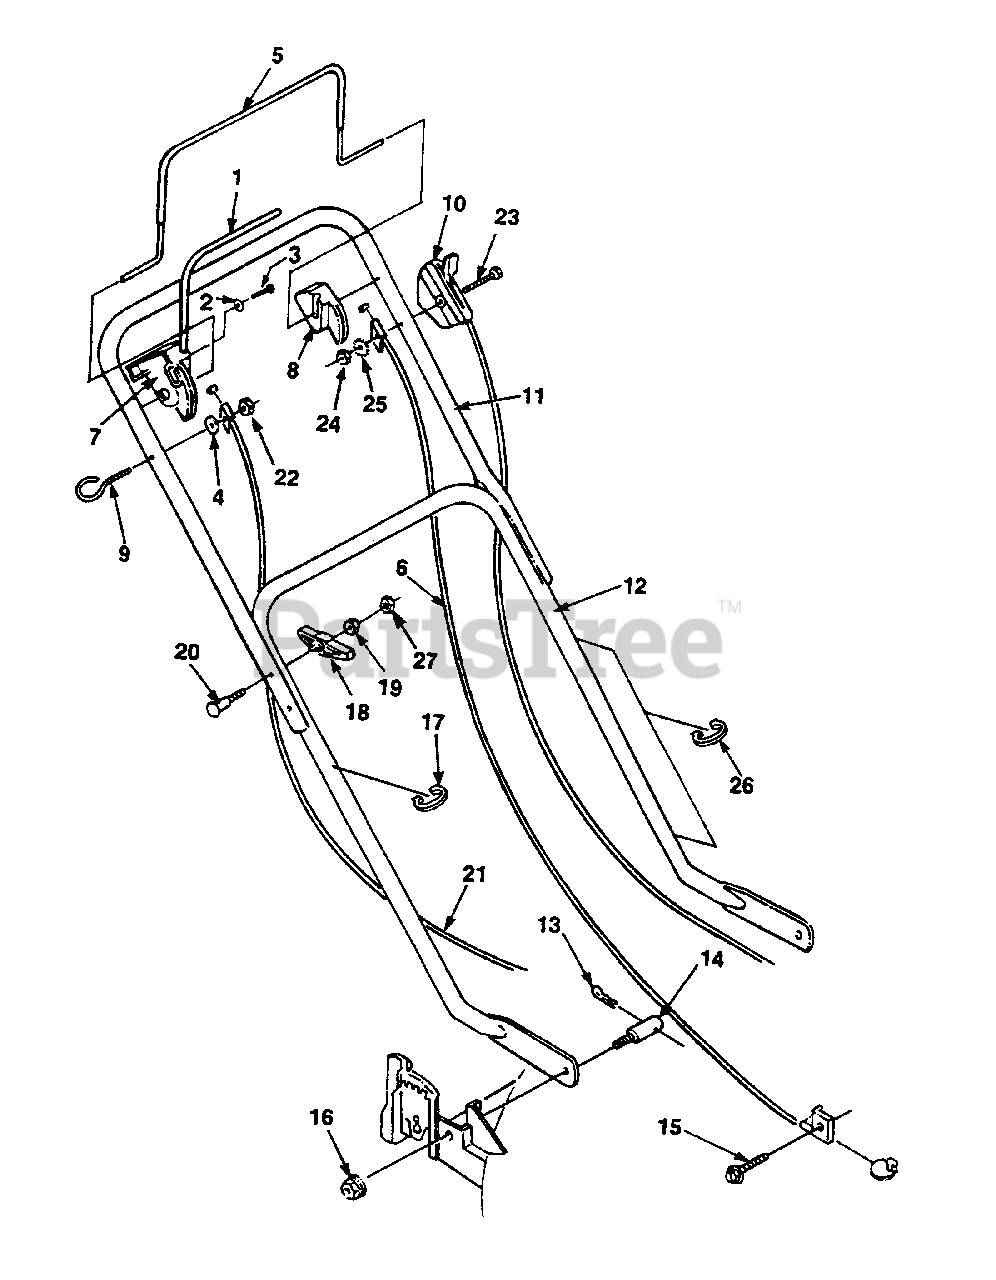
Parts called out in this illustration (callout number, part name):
1	TRACTION LEVER ASSY.
2	WASHER- Flat 1/4"
3	SCREW- Hex 10-16 x 1/2"
4	WASHER
5	BAIL- Brake control
6	CONTROL- Manual start
7	ACTUATOR- R.H.
8	ACTUATOR- L.H.
9	EYEBOLT- 1/4-20 x 1 3/4"
10	CONTROL- Throttle
11	HANDLE- Upper
12	HANDLE- Lower
13	PIN- Hair
15	SCREW- 10-24 x 1/2"
16	NUT- Flanged 5/16-18
17	CLAMP- Cable single
18	KNOB- Handle
19	NUT- Hex 5/16-18
21	CABLE- Traction control
22	NUT- Hex 1/4-20
23	BOLT- Sq. neck
24	NUT- Hex 1/4-20
25	WASHER- External tooth 1/4"
26	CLAMP- Double
27	NUT- Hex lock 5/16-18
